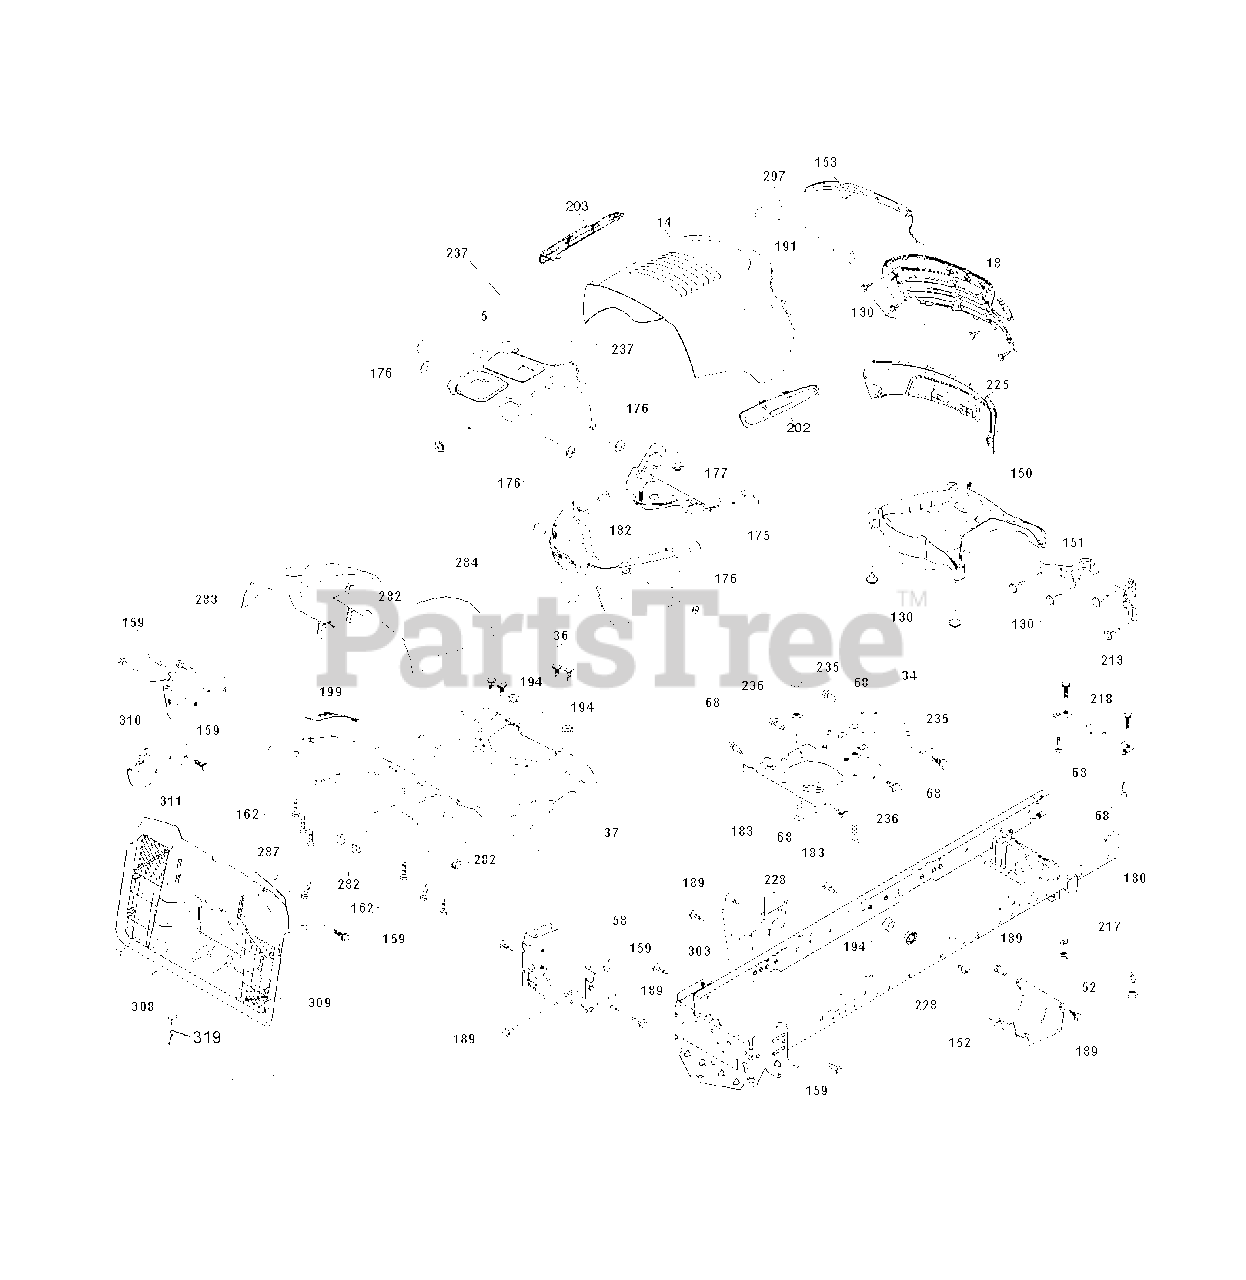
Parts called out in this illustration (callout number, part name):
34	PLATE.ENGINE.WELDED.CHASSIS
36	SCREW 5/16"
52	LOCKNUT
58	DRAWBAR UPPER 2PC SMALL FENDER
130	SCREW.#10 X 0.750.BOS THREAD
151	BRACKET.PIVOT.ALPHA.LT
152	SHIELD BROWNING
159	SCREW, 3/8-16X3/4
162	SCREW.HI-LO.CONSOLE
175	CROSSMEMBER
176	SCREW.#10-24X5/8.RN.QU
177	BUSHING STEERING
182	DASH.LWER.PREDATOR/HUSQ.LT
183	BOLT.5/16-18X1-1/4 FULL.THREAD
189	SCREW
191	INSERT.REFLECT.PREDATOR.LT.RH
194	NUT LOCK HEX FLANGE 5/16-18
213	BOLT
217	ROD.PIVOT.HOOD
218	X-PIECE.HOOD.STOP.NON/
228	STUD.FASTNER.W/ANTI-ROTATE
235	SPACER FENDER
236	NUT.CENTERLOCK.5/16-
237	PLUG.MOUNT.CARGO.BLK
282	CLIP.RETAINER.CONSOLE.LT.HUSQ
297	REFLECTOR.INSERT.PRED.LH.LT
308	BOLT, 5/16-18 X 1 3/4
